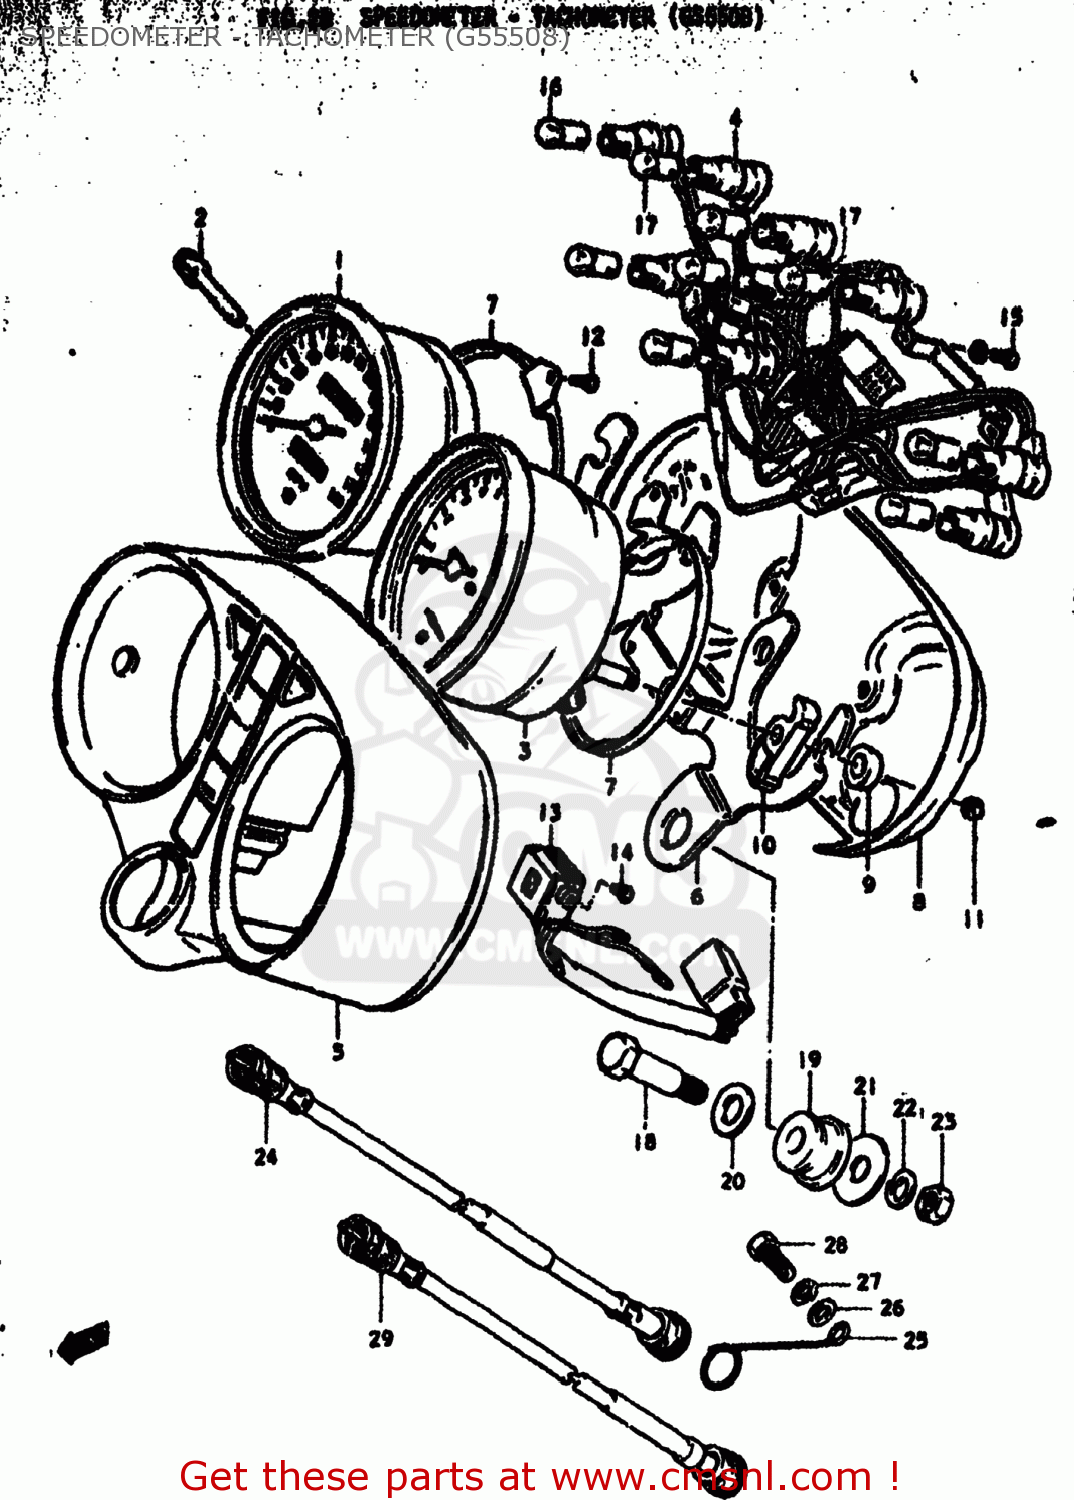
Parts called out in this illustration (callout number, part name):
1	SPEEDOMETER ASSEMBLY
2	KNOB
3	METER,TACHOMETER
4	SOCKET,METER
5	CASE,METER
6	BRACKET,COMBINATION METER
7	PLATE,METER,UNDER
8	PLATE,UNDER
9	CUSHION,METER (A)
10	CUSHION,METER (B)
11	NUT
12	SCREW
13	INDICATOR ASSEMBLY,GEAR POSITION
15	SCREW
16	BULB(12V3.4W,STANLEY,A72A)
17	BULB(12V1.7W,A71A)
18	BOLT(8X31)
19	CUSHION,METER
20	WASHER
21	WASHER (8.5X29X1.6)
22	LOCK WASHER
23	NUT
24	CABLE ASSEMBLY,SPEEDOMETER
25	GUIDE,SPEEDOMETER CABLE
26	WASHER 6MM
27	LOCK WASHER
28	BOLT
29	CABLE ASSEMBLY,TACHOMETER
